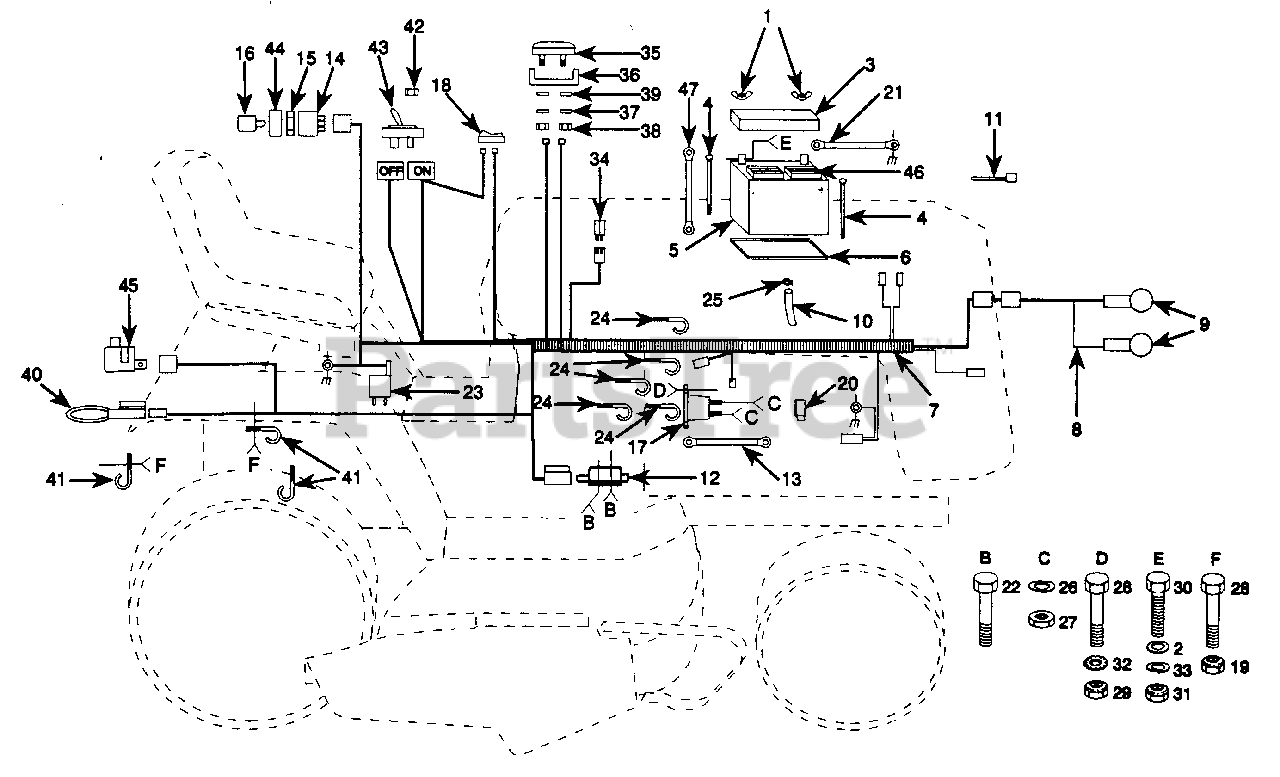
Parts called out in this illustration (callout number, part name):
1	Wingnut 1/4-20 (AYP part number)
2	Washer 9/32 x 5/8 x 16 Gauge (AYP part number)
3	Guard,Terminal (AYP part number)
4	Bolt, Carriage 1/4-20 x 7-1/2 (AYP part number)
5	Battery (AYP part number)
6	Tray, Battery (AYP part number)
7	Harness, Ignition
8	Harness, Light Socket (AYP part number)
9	Bulb, Light (AYP part number)
10	Tube, Battery Tray (AYP part number)
11	Cable Tie (AYP part number)
12	Switch, Interlock, Clutch (AYP part number)
13	Cable, Battery (Battery to Solenoid) (AYP part number)
14	Ignition Switch (AYP part number)
15	Nut, Ignition (AYP part number)
16	Key, Molded (AYP part number)
17	Solenoid (AYP part number)
18	Switch, Light (AYP part number)
19	Nut, Hex 1/4-20 (AYP part number)
20	Terminal Cover (For Solenoid) (AYP part number)
21	Cable, Battery (Battery to Ground) (AYP part number)
22	Screw, Tapping, Hex Head #10-24 UNC x 1/2 Type T (AYP part number)
23	Relay (AYP part number)
24	Clip, Fuel Line (AYP part number)
25	Clamp, Hose (AYP part number)
26	Washer, Lock 1/4 (AYP part number)
27	Nut, Hex Jam 1/4-20 (AYP part number)
28	Bolt, Hex 1/4-20 x 1/2 Grade 5 (AYP part number)
29	Nut, Keps, Hex 1/4-20 (AYP part number)
30	Bolt, Hex 1/4-20 x 3/4 (AYP part number)
31	Nut, Hex 1/4-20 (AYP part number)
32	Washer, Lock, External Tooth 1/4 (AYP part number)
33	Washer, Lock 1/4 (AYP part number)
34	Fuse, 30 Amp. (AYP part number)
35	Ammeter (AYP part number)
36	Bracket, Ammeter (AYP part number)
37	Washer, Lock #10 (AYP part number)
38	Nut (AYP part number)
39	Washer 7/32 x 1/2 x 18 Gauge (AYP part number)
40	Loop, Wire (AYP part number)
41	Clip, insulated (AYP part number)
42	Nut, Hex (AYP part number)
43	Switch, PTO (AYP part number)
44	Bezel, Ignition (AYP part number)
45	Switch, Seat (AYP part number)
46	Cap, Battery (AYP part number)
47	Cable, Battery (Starter to Solenoid) (AYP part number)
